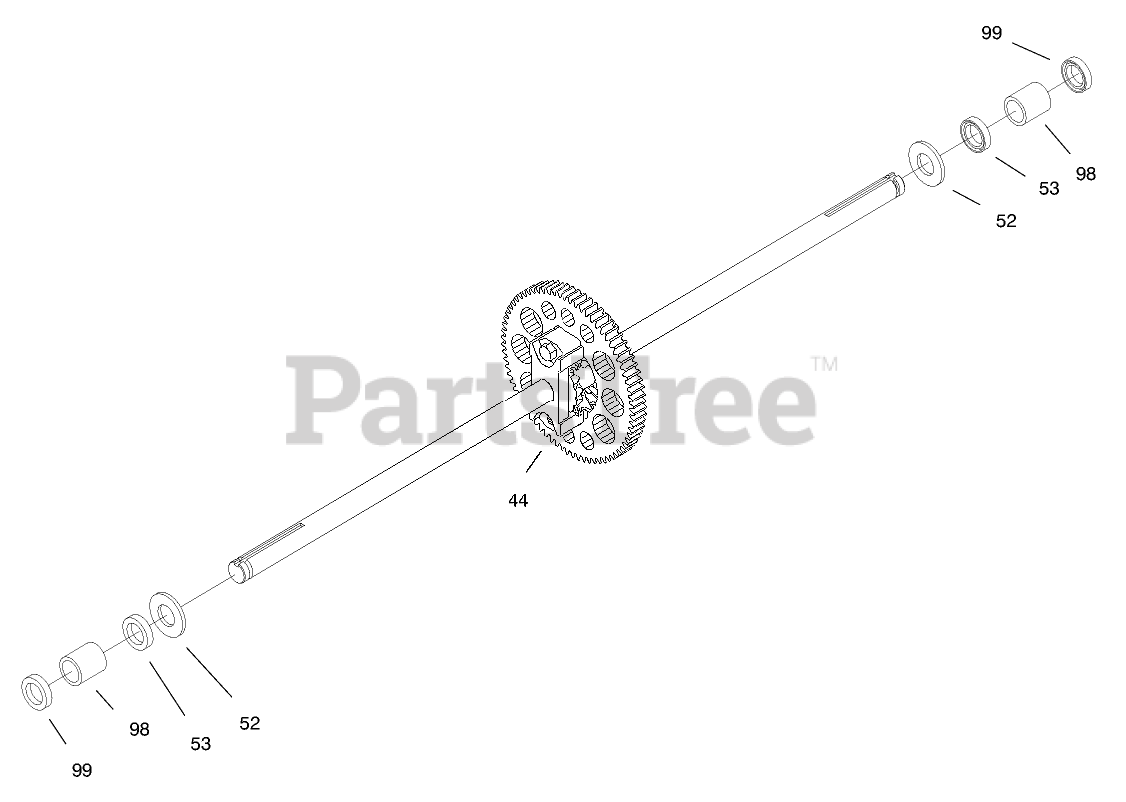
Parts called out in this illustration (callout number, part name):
44	ASM - DIFFERENTIAL
52	WASHER
53	SEAL
98	SLEEVE - BEARING
99	SEAL - WIPER
